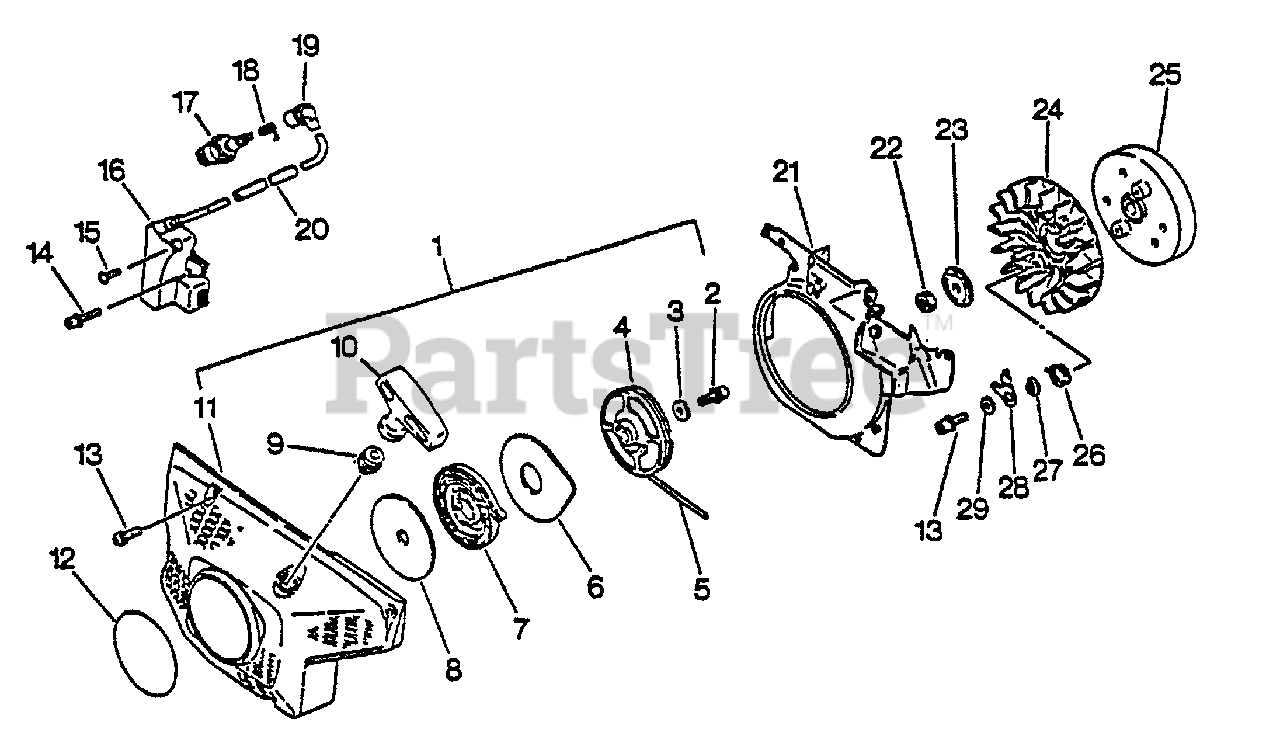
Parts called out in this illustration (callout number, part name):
1	STARTER ASSY
2	SCREW - 5X14
3	WASHER - 5
4	REEL, ROPE
5	ROPE, STARTER - 4X950
6	PLATE, STARTER
7	SPRING, REWIND
8	PLATE, STARTER
9	GUIDE, ROPE
10	GRIP, STARTER
11	CASE, STARTER
12	LABEL - ECHO
13	SCREW - 5X20
14	SCREW - 4X20
15	SCREW - 4X8
16	COIL, IGNITION
17	SPARK PLUG -- BPM-6A
18	TERMINAL, SPARK PLUG CAP
19	CAP, SPARK PLUG
20	TUBE
21	SHIELD, FAN
23	WASHER - CUP
25	FLYWHEEL
26	SPRING, RETURN
28	PAWL, STARTER
29	WASHER - 5
